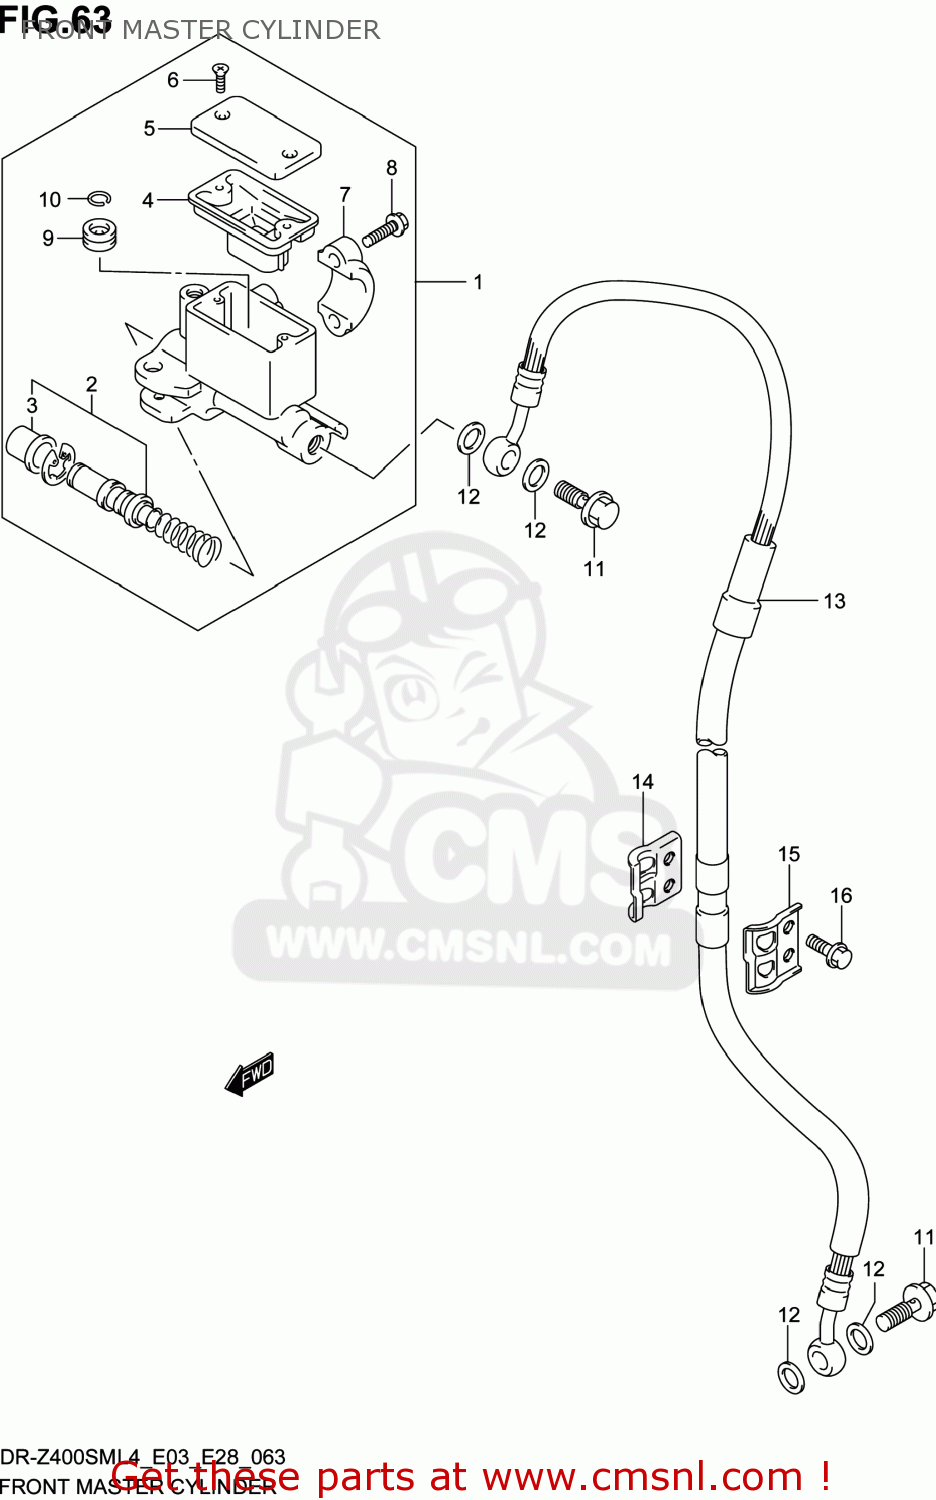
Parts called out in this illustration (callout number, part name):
1	CYLINDER ASSY,FR MASTER
2	PISTON/CUP SET
3	BOOT
4	DIAPHRAGM
5	CAP
6	SCREW
7	HOLDER
8	BOLT
9	SEPARATOR
10	RING
11	BOLT UNION
12	WASHER(10X15X1.5)
13	HOSE,FR BRAKE
14	CLAMP,FR BRAKE HOSE INNER
15	CLAMP,FR BRAKE HOSE OUTER
16	BOLT(6X16)
